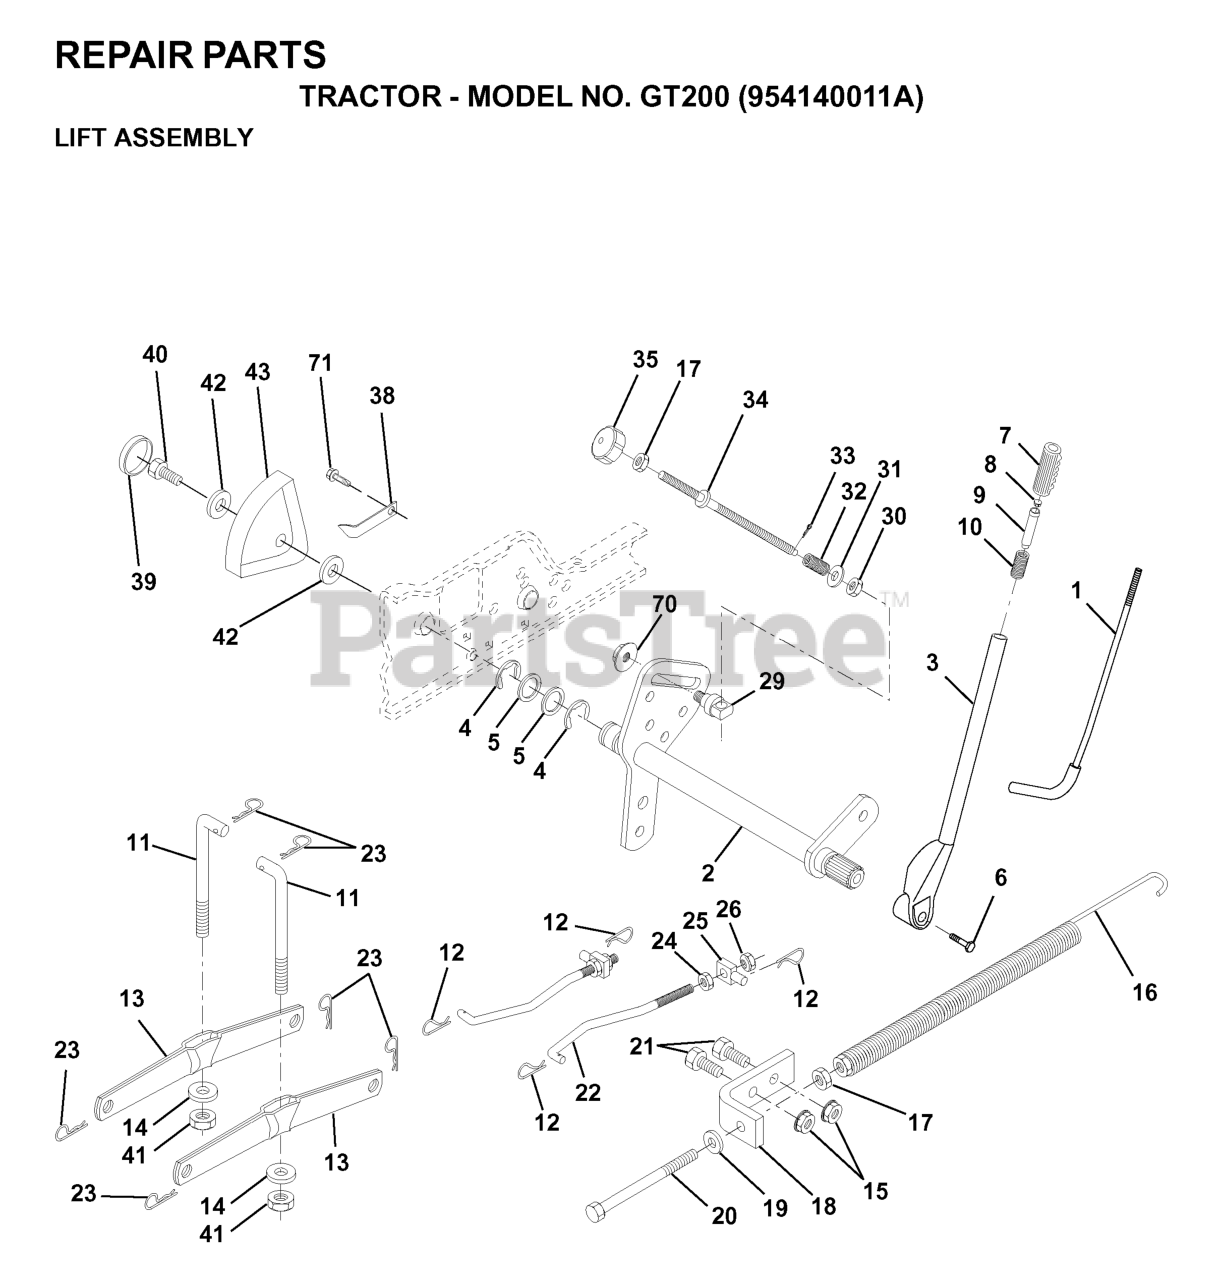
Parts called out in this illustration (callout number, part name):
1	LEVER ROD LT
2	SHAFT ASM., LIFT VGT
3	LIFT LEVER KIT
5	Washer 29/32 x 1 - 1/4 x 16 Ga.
6	BOLT
7	GRIP HANDLE
8	PLUNGER BUT KIT
9	PLUNGER BUT KIT
10	SPRING**
11	LINK LIFT
12	SPRING RETAINER
13	ARM.REAR.SUSPENSION
14	BEARING PIVOT
16	LIFT SPRING
17	NUT
19	WASHER
21	BOLT
22	FRONT LINK
23	RETAINER-SPRNG RB
24	NUT.HEX.JAM.1/2-13
25	TRUNION
26	NUT.LK.W/WSH.1/2.
32	SPRING.COMP.INF.H
33	COTTER PIN
34	ROD.LIFT.ADJUSTABLE
35	KNOB INF 3/8-16
36	SCREW
38	POINTER HGT
40	SCREW.THDROL.5/16-18X3/4.TTY
41	NUT CROWNLOCK 3/8-24
43	HEIGHT INDICATOR
70	NUT
